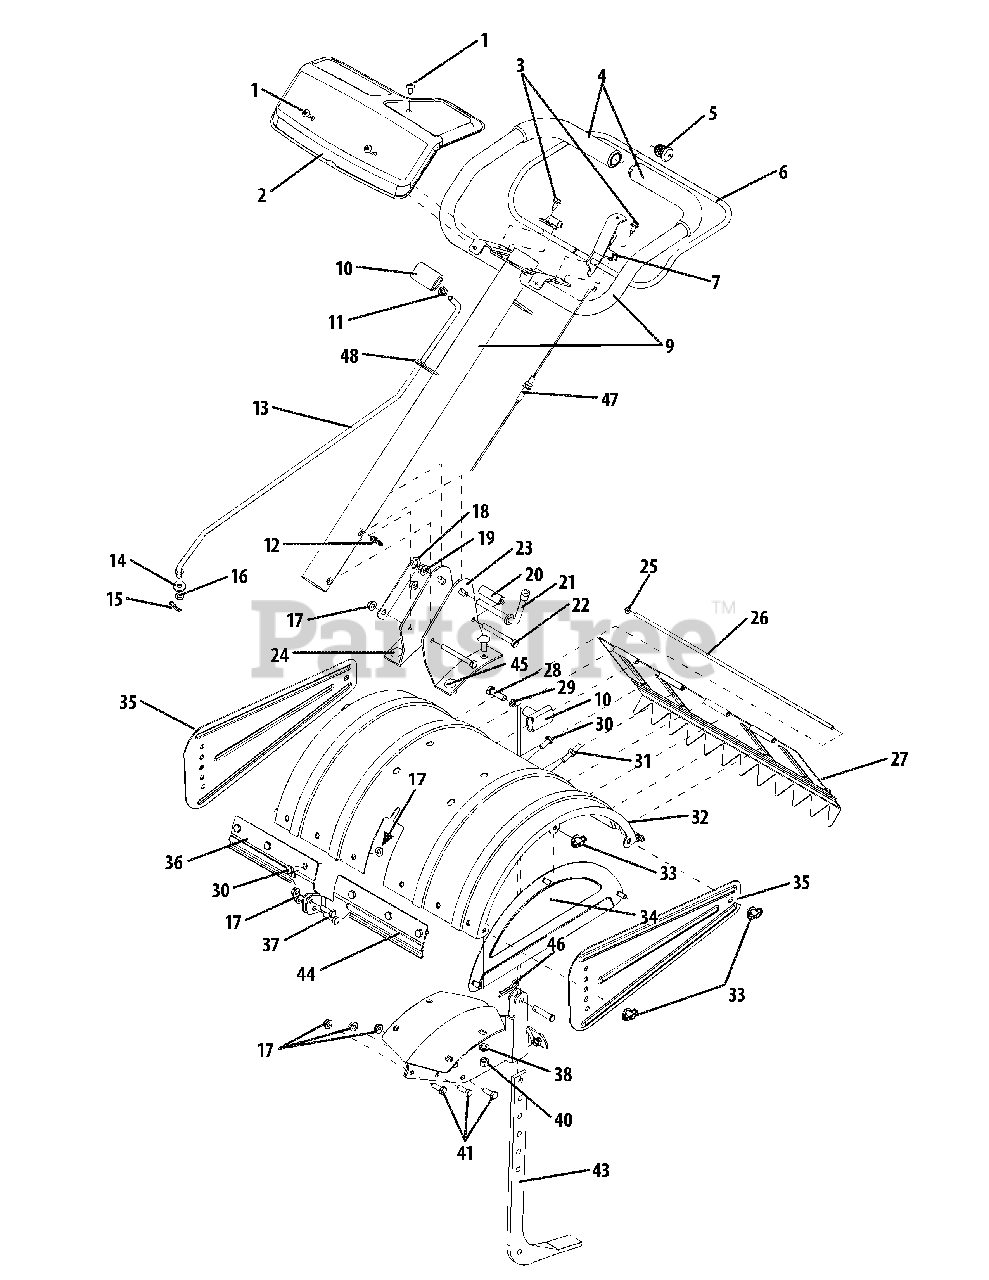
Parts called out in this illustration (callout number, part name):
1	Tap Screw, 1/4-14 x.625
4	Foam Grip
5	End Plug
7	Return Bracket, Left
8	Return Bracket, Right
11	Jam Nut, 3/8-16
12	Cable Clip
13	Shift Control
14	Rubber Washer, .33 ID x.87 OD
15	Cotter Pin
16	Flat Washer, .344 ID x.62 OD
17	Hex Flange Lock Nut,5/16-18
18	Retainer Bracket
19	Flange Lock Nut, 3/8-24
20	Spacer, .322 ID x.625 OD
21	Handle Adjustment Crank
22	Hex Screw,5/16-18 x 3.0
28	Hex Cap Screw, 3/8-16 x 1.25
29	Flat Washer, .375 ID x.620 OD
30	Hex Cap Screw, 5/16-18 x.75
31	Hex Screw, 5/16-18 x.75
36	Shield Bracket, Right
37	Hex Cap Screw, 5/16-18 x 1.0
38	Lock Washer,3/8
39	Clevis Pin
40	Hex Nut, 3/8 -16
41	Hex Cap Screw,5/16-18 x.875
44	Shield Bracket, Left
45	Carriage Bolt 3/8-16 x 1.0
46	Cotter Pin
47	Clutch Cable
48	Rod Control Bushing
